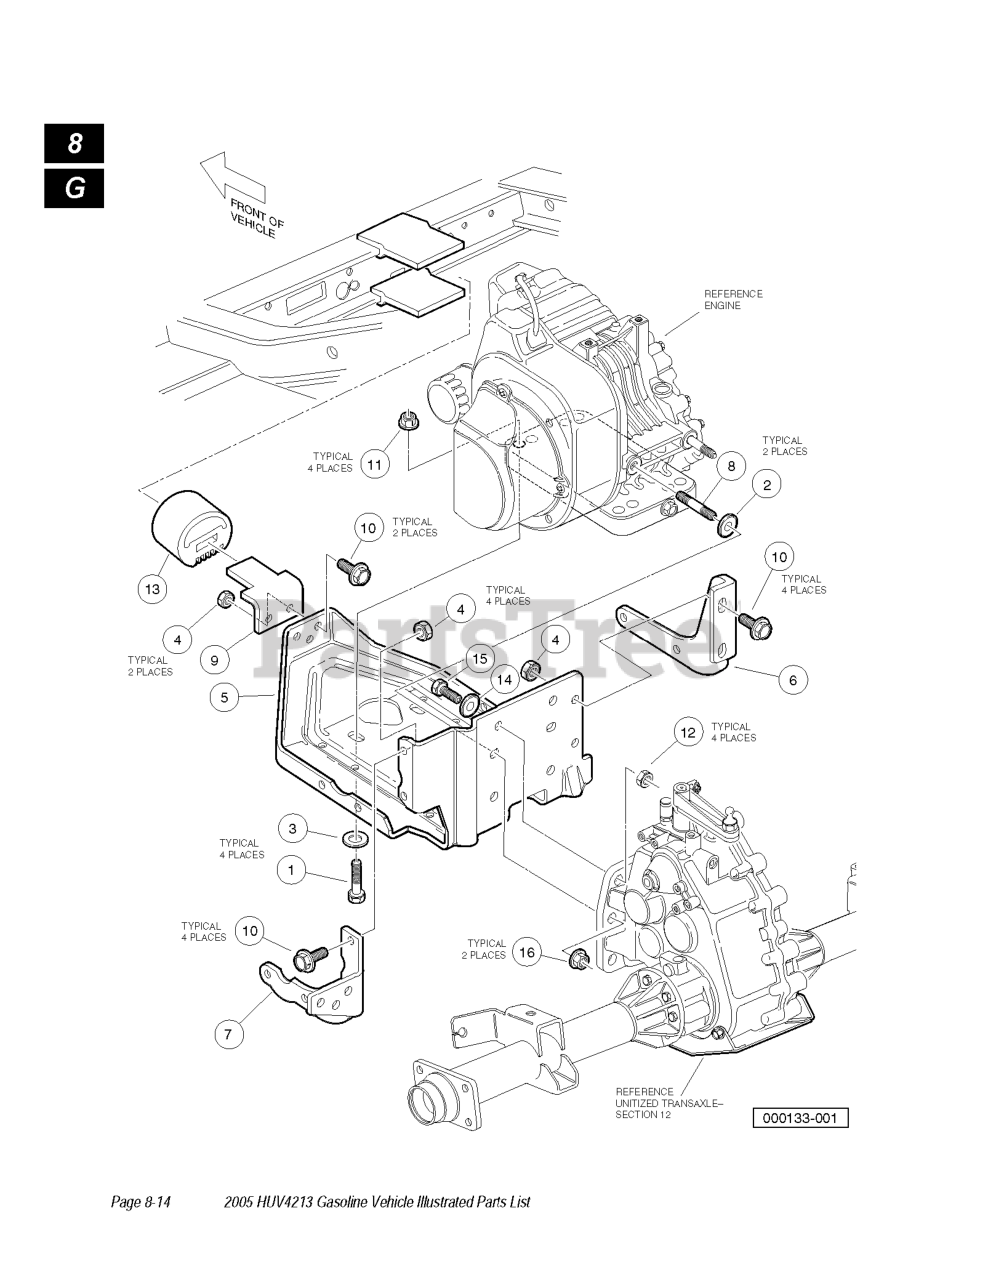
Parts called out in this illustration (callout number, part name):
1	BOLT HEX HEAD
2	WASHER, 5/16 FLAT
5	PLATE, ENGINE MOUNTING
6	PTO SIDE STIFFENER
7	STIFFENER, FLYWHEEL SIDE
8	STUD, M8-1.25 X 50MM 2-ENDED
9	SNUBBER BRACKET
10	SCREW, 5/16-24 X .875 GR8 FLNG
11	LOCKNUT, 5/16-18 HEX FLANGE
12	LOCKNUT, 3/8-16 FLANGED DIMPLE
13	INNER FRAME SNUBBER
14	WASHER, 3/8 FLAT
16	NUT, M8-1.25 FLANGED HEX
